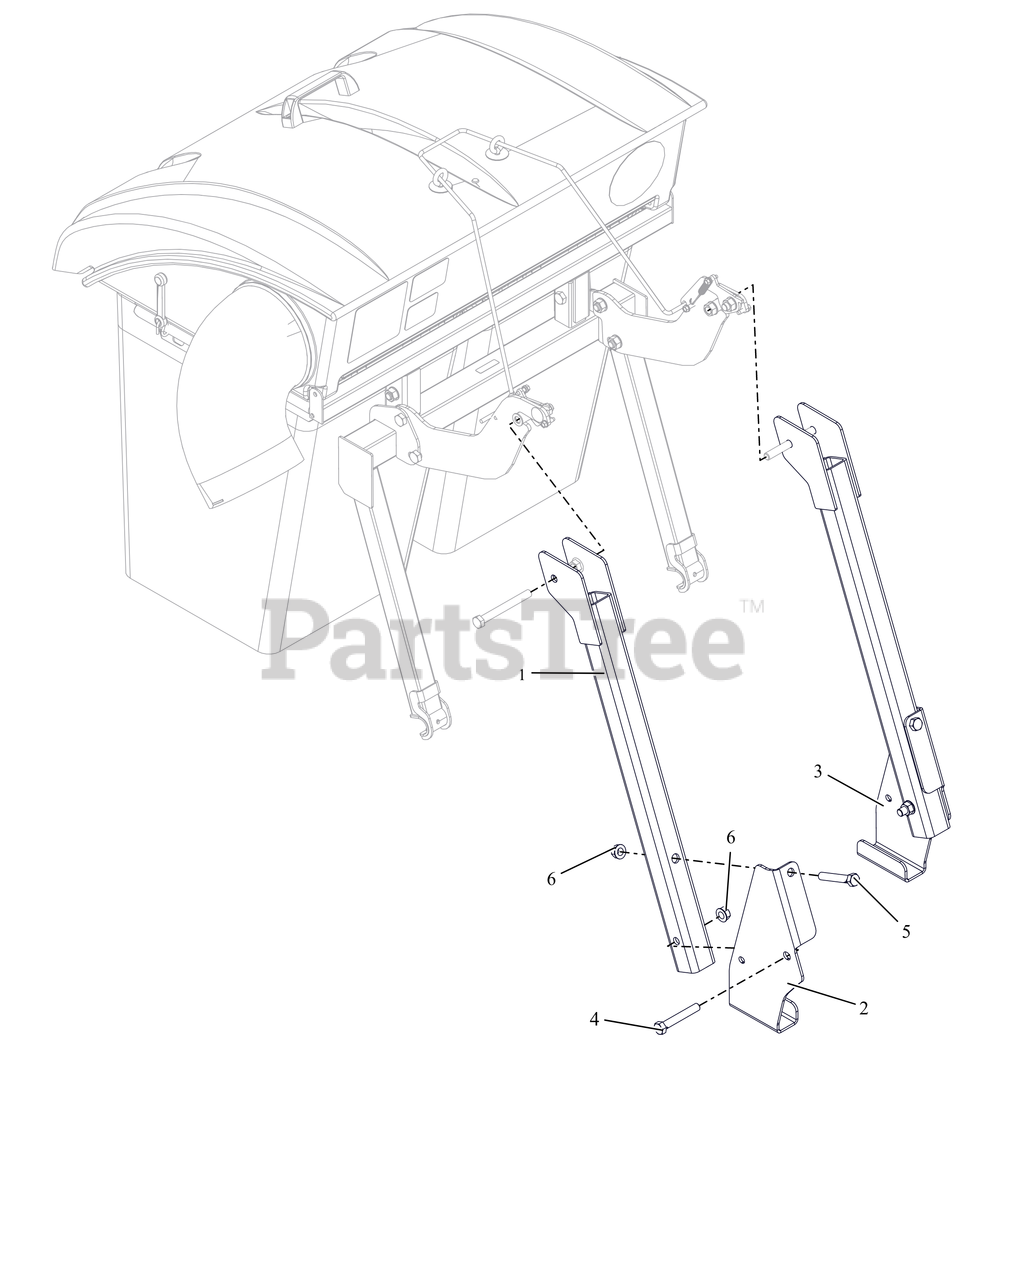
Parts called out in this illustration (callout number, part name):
1	WLDMT, BAGGER FRONT MOUNT
2	BRKT, ROPS SUPPORT - RH
3	BRKT, ROPS SUPPORT -LH
4	BLT,HEX .50-13X3.25 G5 ZCC
5	BLT, HEX .50-13X3.00 G5 ZCC
6	NUT-LK-TOP-FLG .500-13 GF ZCC
